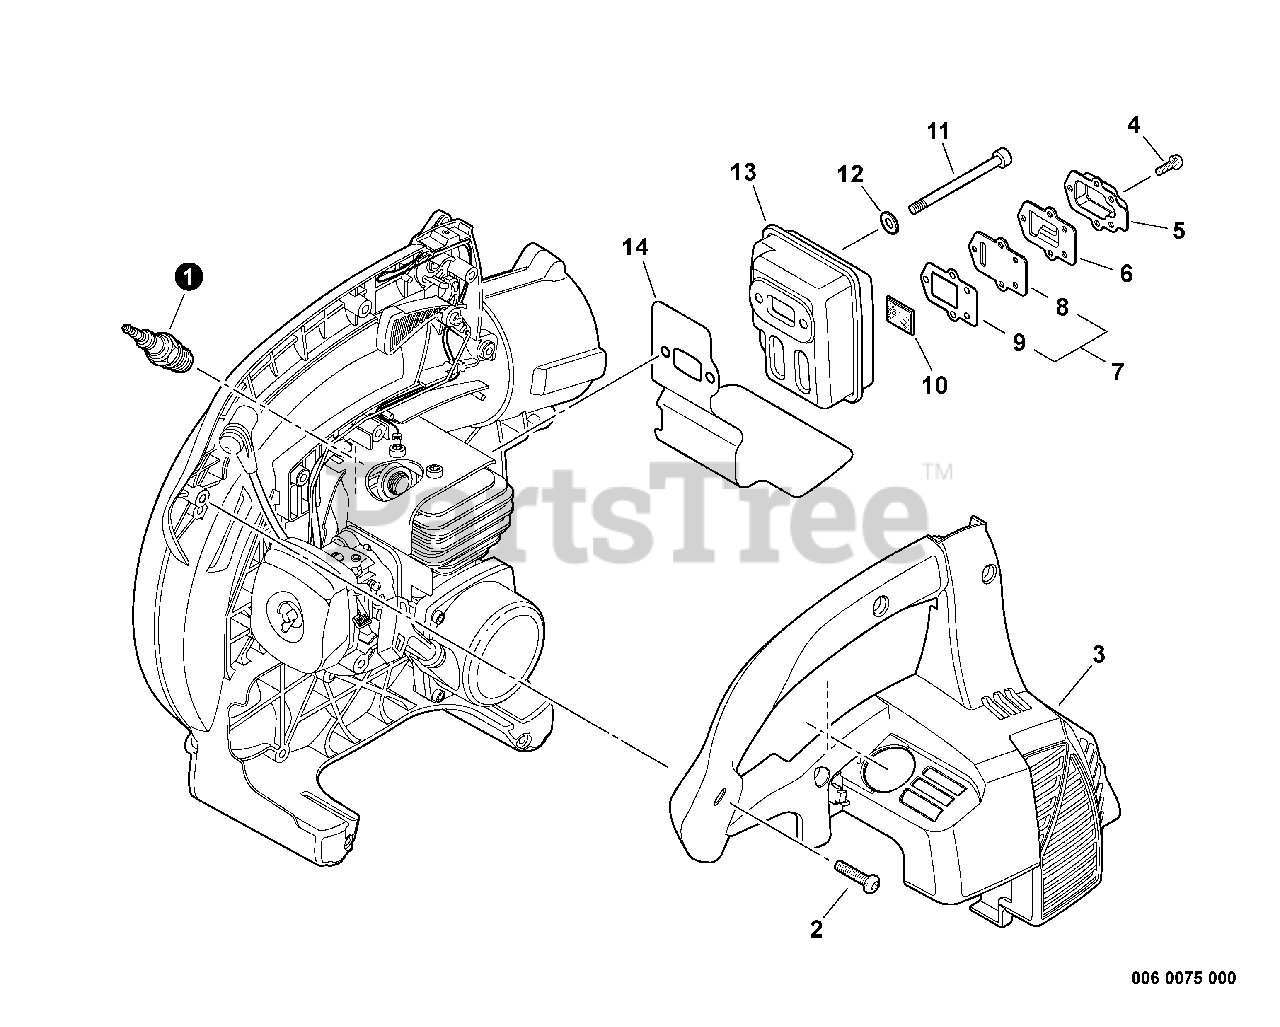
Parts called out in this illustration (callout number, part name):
1	SPARK PLUG -- BPM-8Y
1	SPARK PLUG -- BPMR-8Y
2	SCREW - 5X20
3	COVER, ENGINE
4	SCREW - 4X8
5	GUIDE, EXHAUST - OUTER
6	GUIDE, EXHAUST - INNER
7	EXHAUST GUIDE KIT
8	GUIDE, EXHAUST
9	GASKET, EXHAUST
10	SCREEN, SPARK ARRESTOR
11	SCREW - 5X55
12	WASHER - 5
13	MUFFLER
14	SHIELD, EXHAUST
